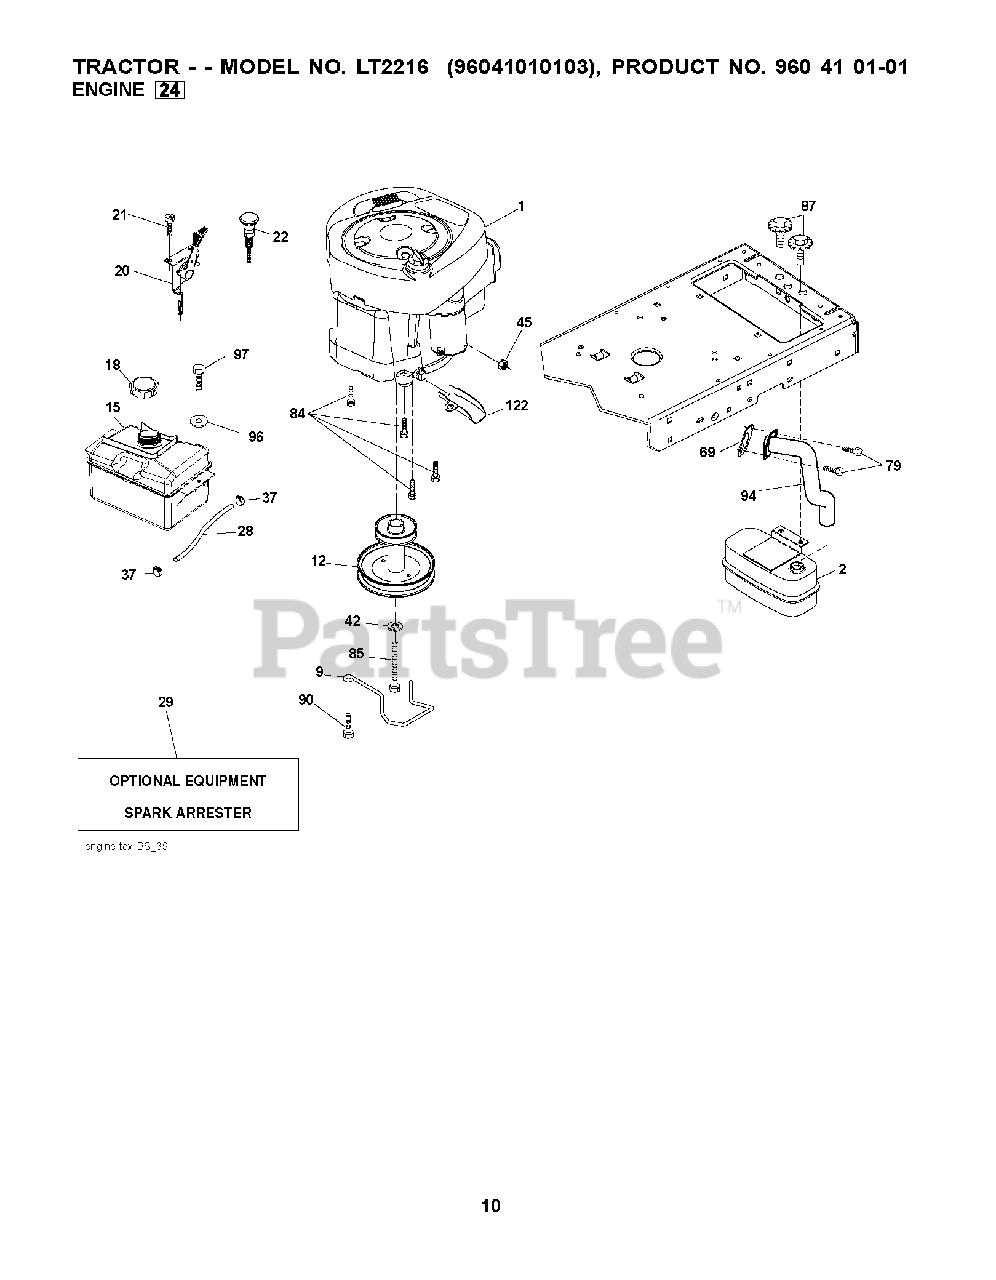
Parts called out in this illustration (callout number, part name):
2	MUFFLER.SINGLE.CYL.KOHL/B&S
9	KEEPER.BELT.ENGINE.3.25
12	PULLEY ENGINE
15	TANK FUEL FRT 1.5 GAL
18	CAP ASM.FUEL.2.25"FR.
20	CONTROL.TH/CK.C.
21	SCREW.#10 X 0.750.BOS THREAD
28	LINE.FUEL.20
29	ARRESTER SPARK (OPTIONAL)
37	HOSE CLAMP
42	LOCKWASHER
45	NUT
69	REPL BY 532 27 22-93
79	SCREW.SOCKET HD.5/16-1
84	SCREW.3/8-16
85	BOLT HEX 7/16-20X4-1/4"
87	BOLT, 5/16-18 X 1 3/4
90	SCREW 3/8-16X1
94	EXHAUST.TUBE.B&S.
97	SCREW HEXWSHR 1/4-20X3/4
122	EXTENSION DRAIN OIL
